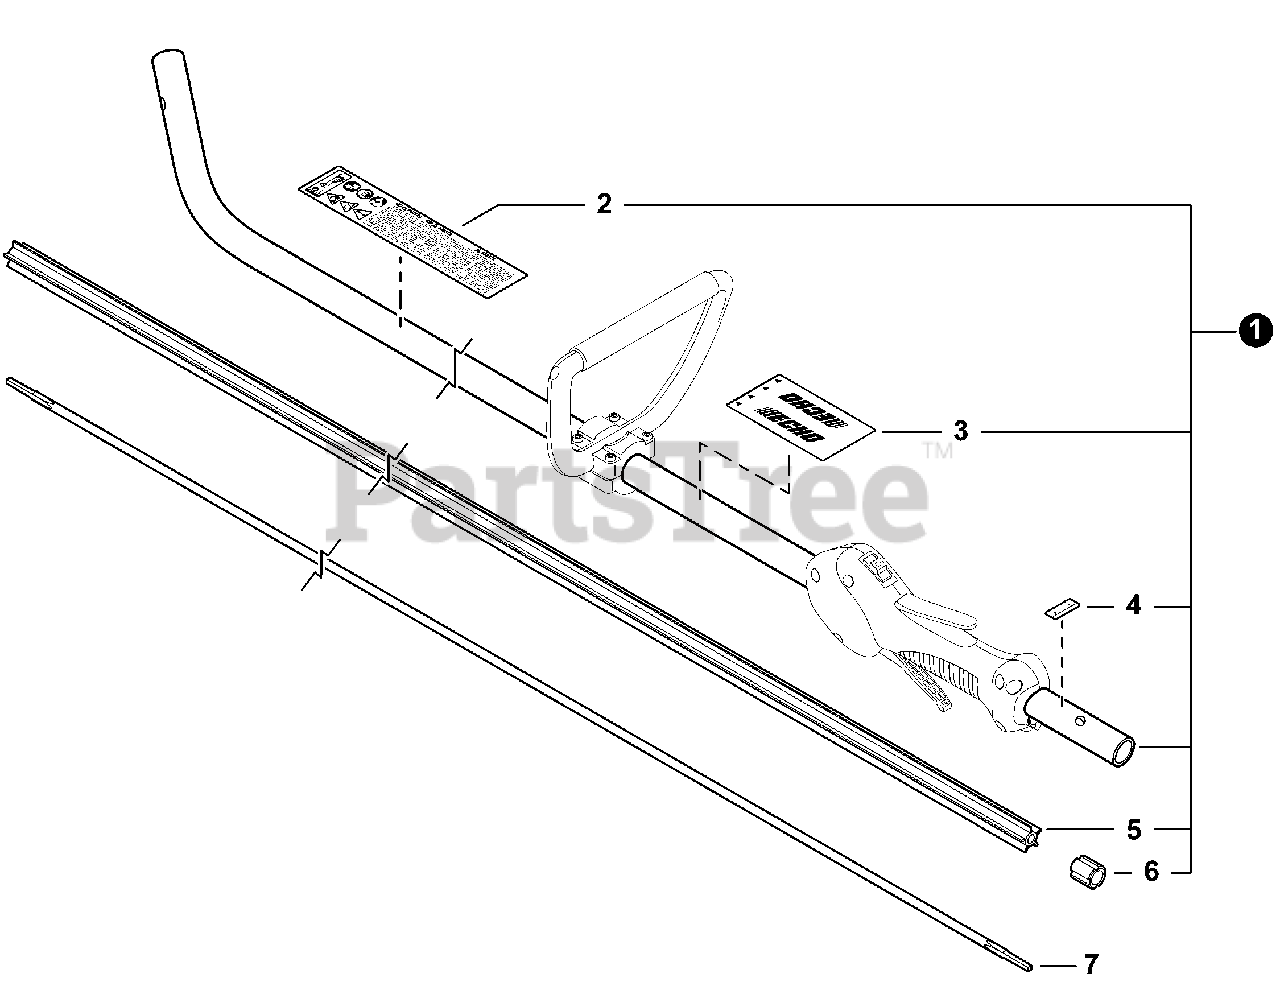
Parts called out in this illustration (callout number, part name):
1	MAIN PIPE ASSY
2	LABEL, CAUTION
3	LABEL, HANDLE LOCATION
4	LABEL - ALIGNMENT
5	LINER, FLEXIBLE 21.6×1420
7	DRIVESHAFT - FLEXIBLE
